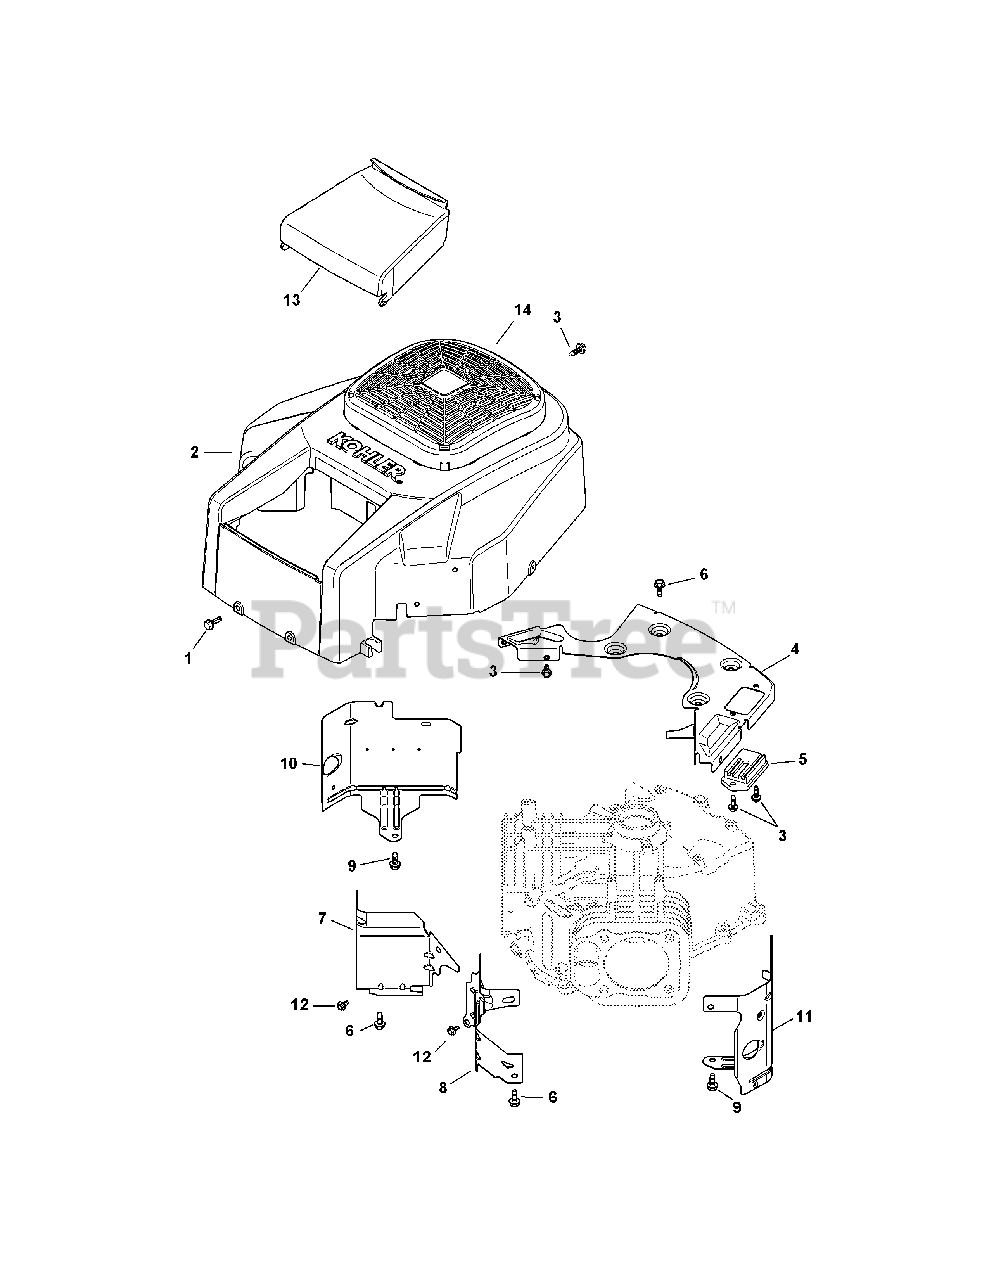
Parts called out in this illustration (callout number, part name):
1	Screw, M6 x 1.7 x 18
2	Blower Housing Kit
3	Flange Screw, M5 x .8 x 16
4	Backing Plate Kit
5	Regulator/Rectifier
6	Flange Screw, M6 x 1.0 x 16
7	Valley Baffle, #1 Cylinder
8	Valley Baffle, #2 Cylinder
9	Flange Screw, M6 x 1.0 x 10
10	Cylinder Barrel Baffle, #1 Side
11	Cylinder Barrel Baffle, #2 Side
12	Flange Screw, M5 x .8 x 10
13	Air Cleaner Cover
